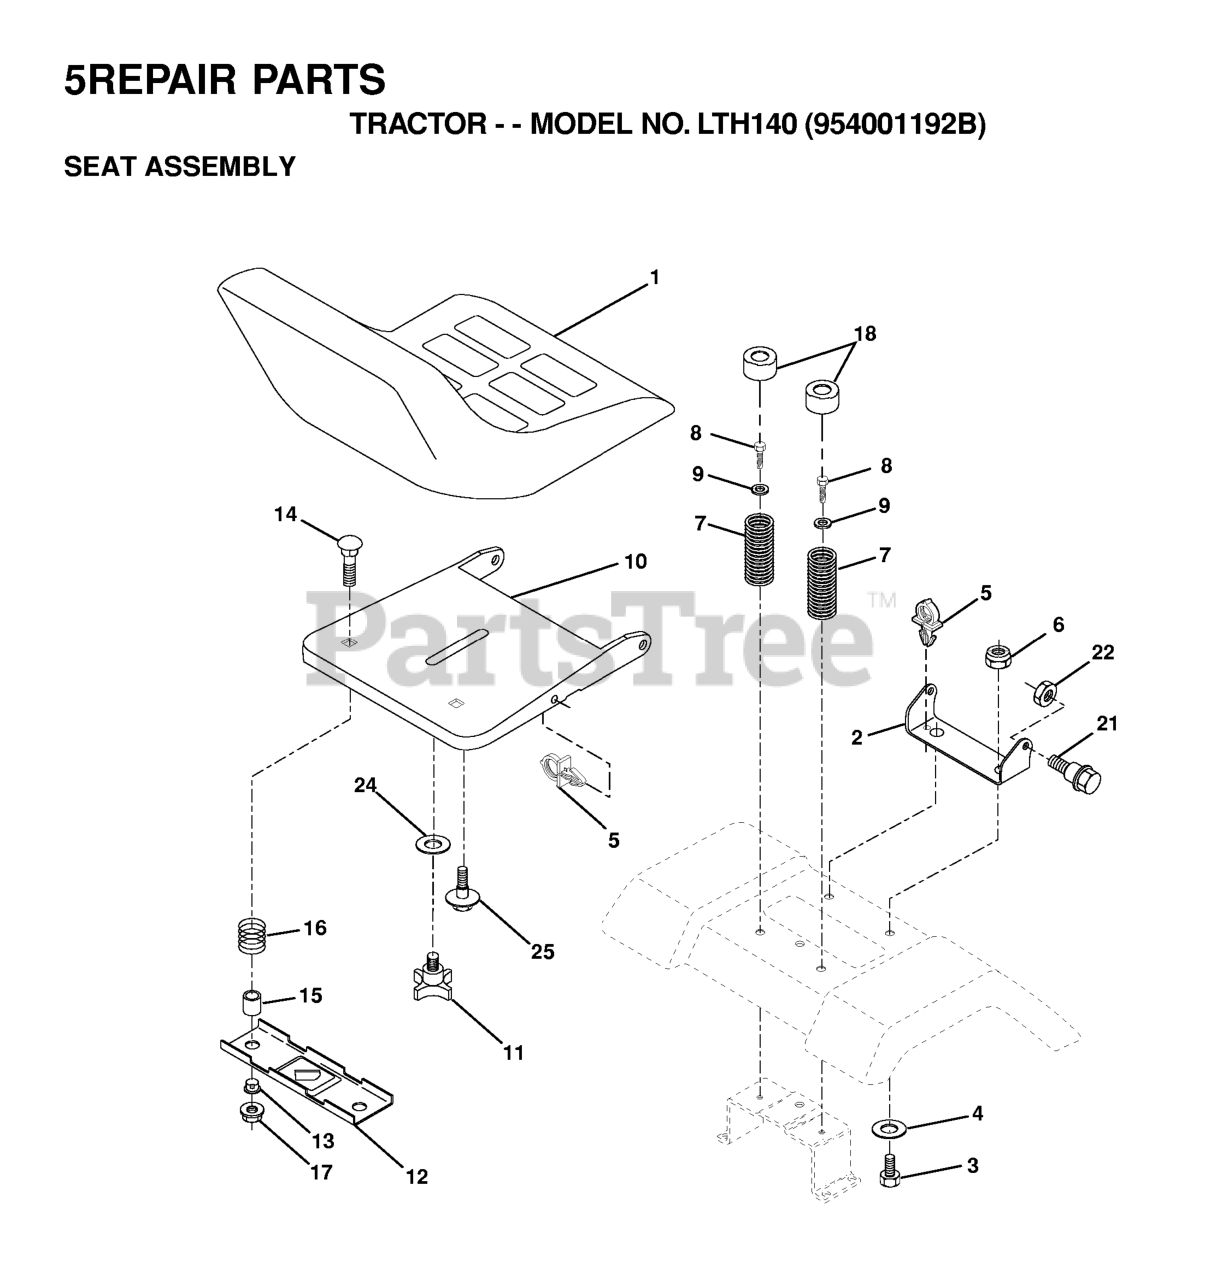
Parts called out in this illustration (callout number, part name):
1	SEAT
2	SEAT PIVOT BRKT
3	BOLT
6	NUT
7	SPRING COMPRESSION
8	SCREW GTV
9	WASHER
10	SEAT PAN
11	KNOB 1/2" YT
12	BRKT SWITCH
14	Bolt Rdhd. Sht. Nk 1/4-20 x 1-3/8
15	SPACER SPLIT 28X.96
17	NUT T
18	CAP SPRING
21	BOLT.SHOULDER.5/16-18
22	NUT.71038.31-18.HEX.NYLOCK
25	BOLT,SHOULD
